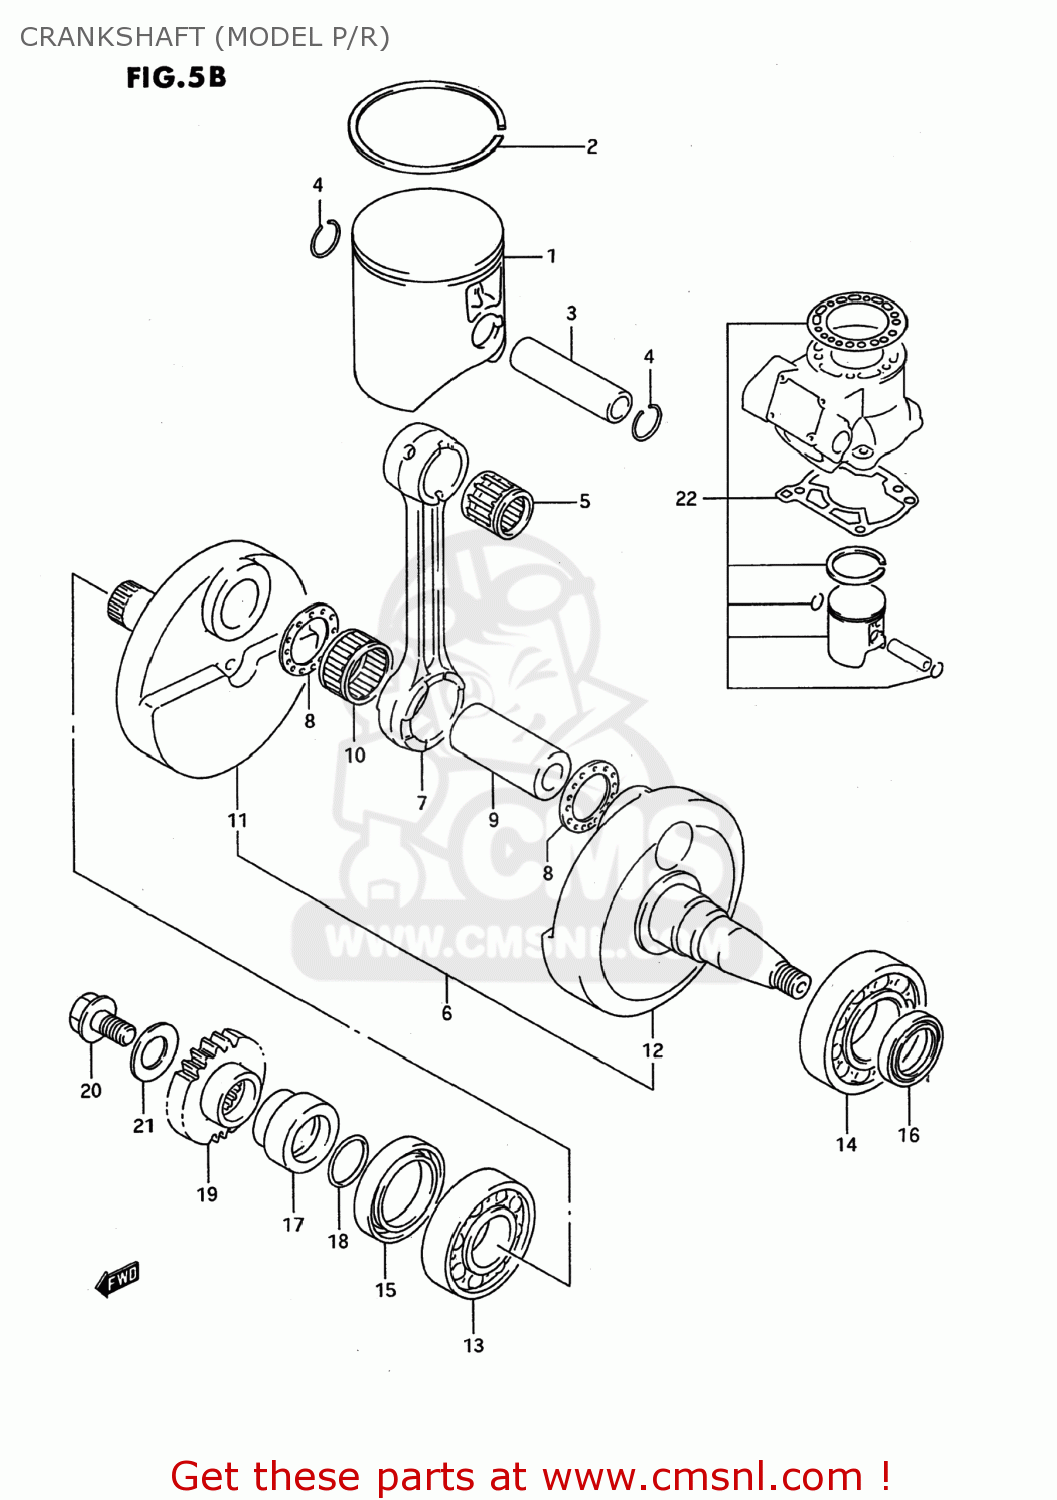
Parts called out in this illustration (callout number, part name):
1	PISTON (67.00MM)
2	RING,PISTON
3	PIN,PISTON
4	CIRCLIP
5	BEARING(18X23X22)
6	CRANKSHAFT ASSEMBLY
7	ROD,CONNECTING
8	WASHER(24X38.5X1.5)
9	PIN,CRANK
10	BEARING(24X30X20)
11	CRANKSHAFT,R
12	CRANKSHAFT,LEFT
13	BEARING(25X62X17)
14	BEARING 28X68X18
15	SEAL,OIL(36X52X7)
16	SEAL,OIL(25X37X6)
17	SPACER,PRIMARY DRIVE GEAR
18	O RING(D:2.4,ID:21.8)
19	GEAR,PRIMARY DRIVE (NT:
20	BOLT,PRIMARY DRIVE GEAR
21	WASHER
22	TOP END KIT,ENGINE
